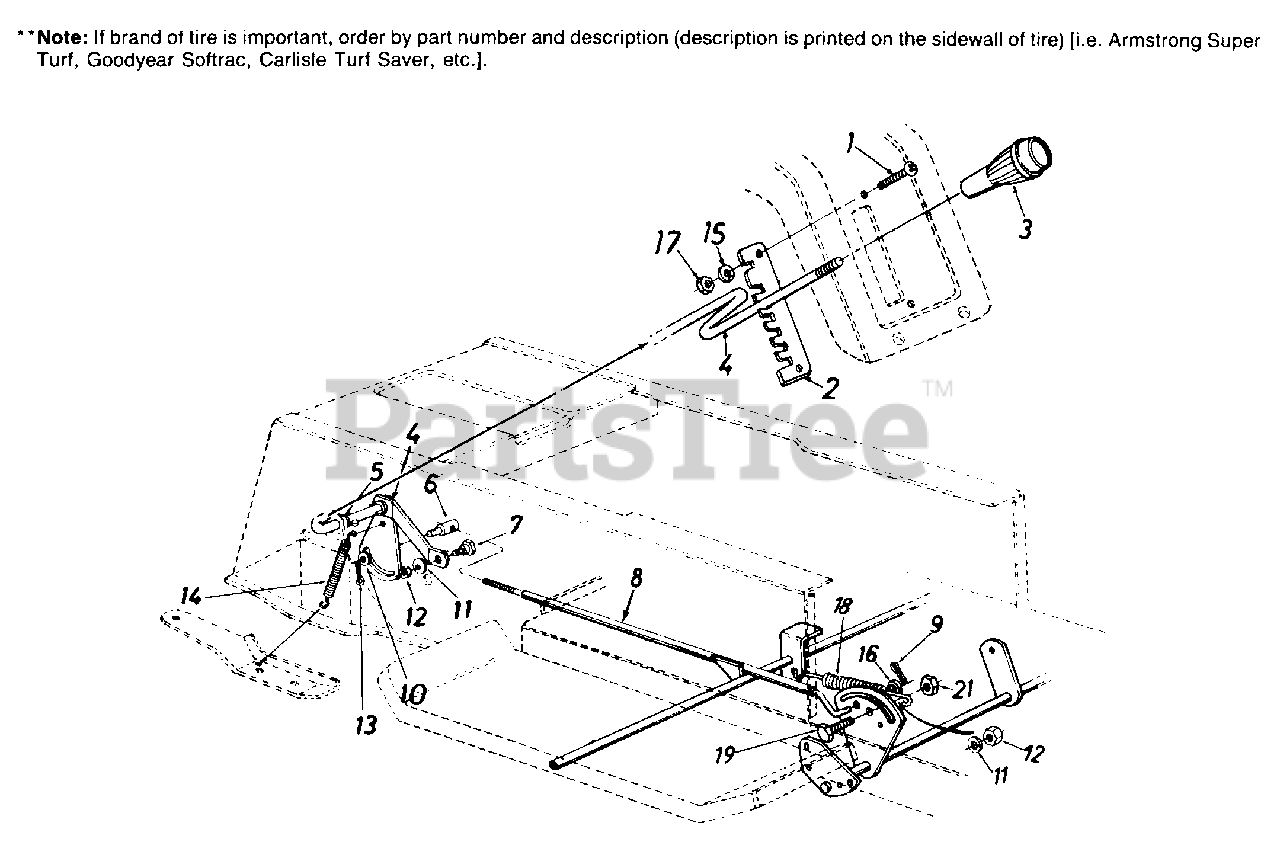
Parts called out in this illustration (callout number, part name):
1	Truss Mach. Scr. 1/4-20 x .62" Lg.
2	Speed Selector Plate
3	Shift Knob
4	Speed Selector Cam Ass'y.
5	Flat Washer .53" I.D. x .93"
6	Ferrule 3/8-24 x .37" Dia.
7	Shoulder Bolt .435" Dia. x .160
8	Speed Control Rod Ass'y.
9	Cotter Pin 3/32" Dia. x .75"
10	Fl-Wash. .385" I.D. x .62" O.D.
11	L-Wash. 5/16" I.D.
12	Hex Nut 5/16-18 Thd.
13	Cotter Pin 3/32 Dia. x .75"
14	Spring
15	L-Wash. 1/4" I.D.
16	Fl-Wash. .47" I.D. x .88" O.D.
17	Hex Nut 1/4-20 Thd.
18	Ext. Spring 4.75" Lg.
19	Hex Cap Bolt 5/16-18 x 1" Lg. (Grade 5)
21	Hex L-Nut 5/16-18 Thd.
